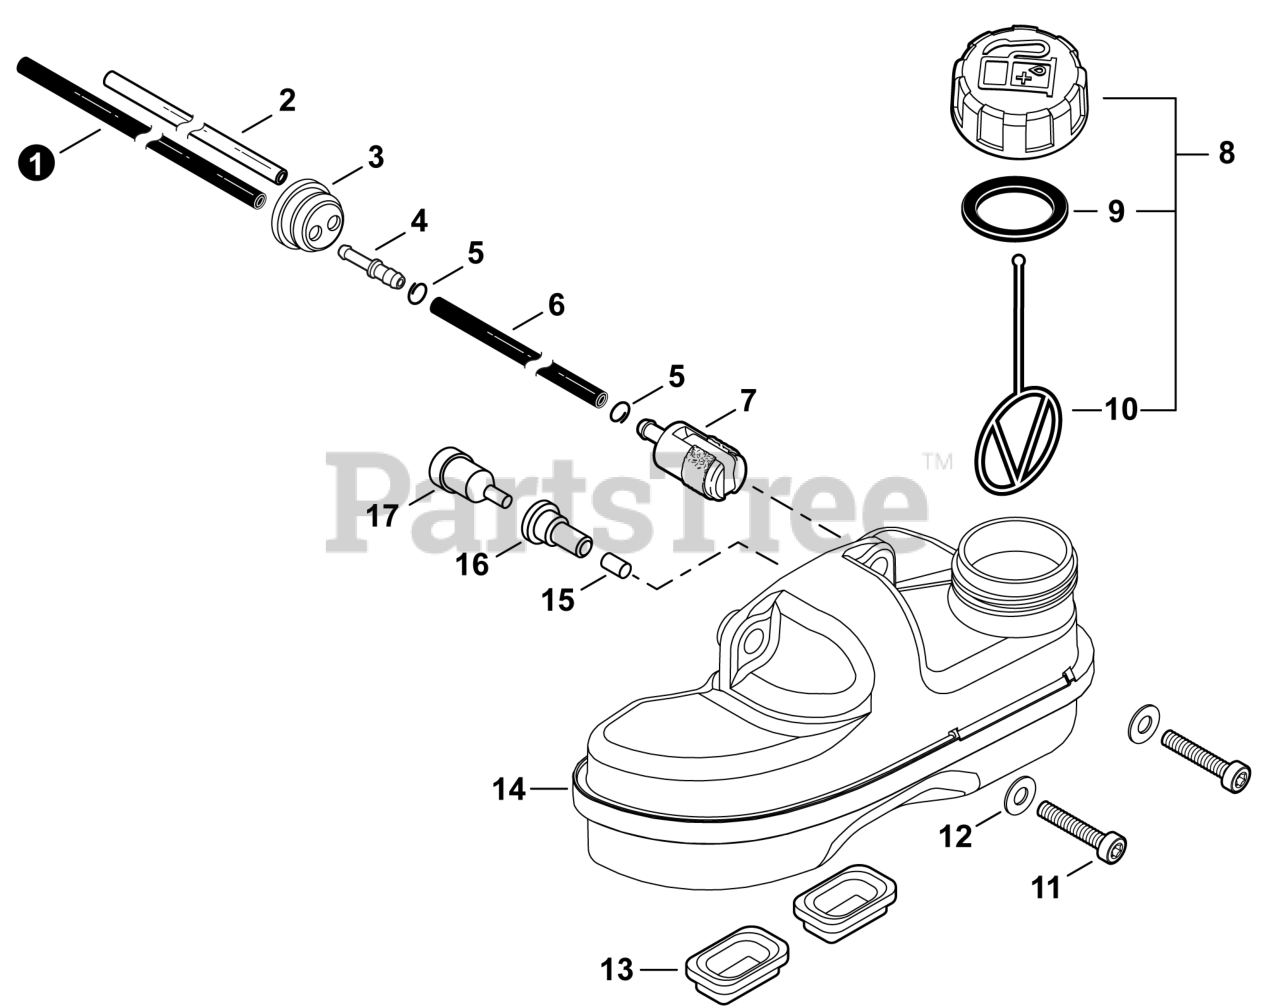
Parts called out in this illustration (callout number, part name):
1	PIPE, FUEL 3×5.5×91 BLACK
2	PIPE, FUEL RETURN 3×6×90 MM CLEAR
3	GROMMET, FUEL
4	CONNECTOR, PIPE Ø5ר3.5
5	CLIP Ø6
6	PIPE, FUEL 3×5×115 BLACK
7	FILTER, FUEL
8	FUEL CAP ASSY, HC-2020
9	GASKET, FUEL CAP
10	FUEL CAP CONNECTOR (L=60MM)
11	BOLT, TORX 5×20
12	WASHER 5.5×12×0.8
13	CUSHION
14	TANK, FUEL
15	FILTER, VENT
16	GROMMET, FUEL
17	VENT ASSY
